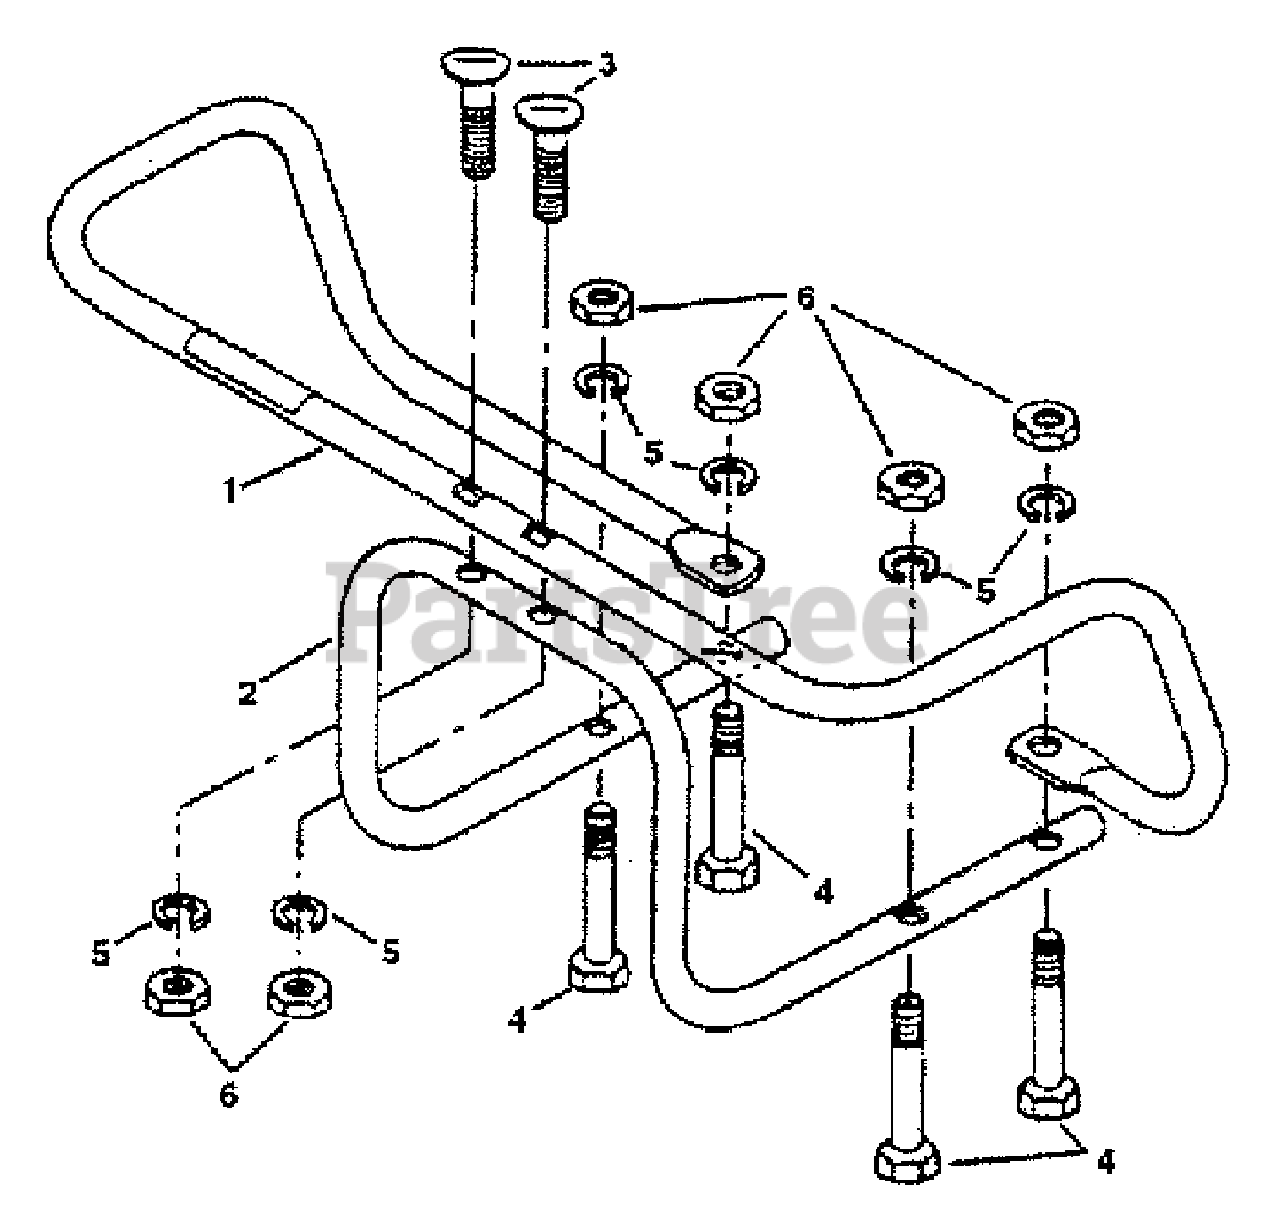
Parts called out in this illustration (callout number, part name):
1	Bumper, Top Section
2	Bumper, Bottom Section
3	Curved Hd. Screw, 5/16-18 x 2 (special)
4	Hex Screw, 5/16-18 x 2-1/2, Grade 5
5	Lockwasher, 5/16
6	Hex Nut, 5/16-18
